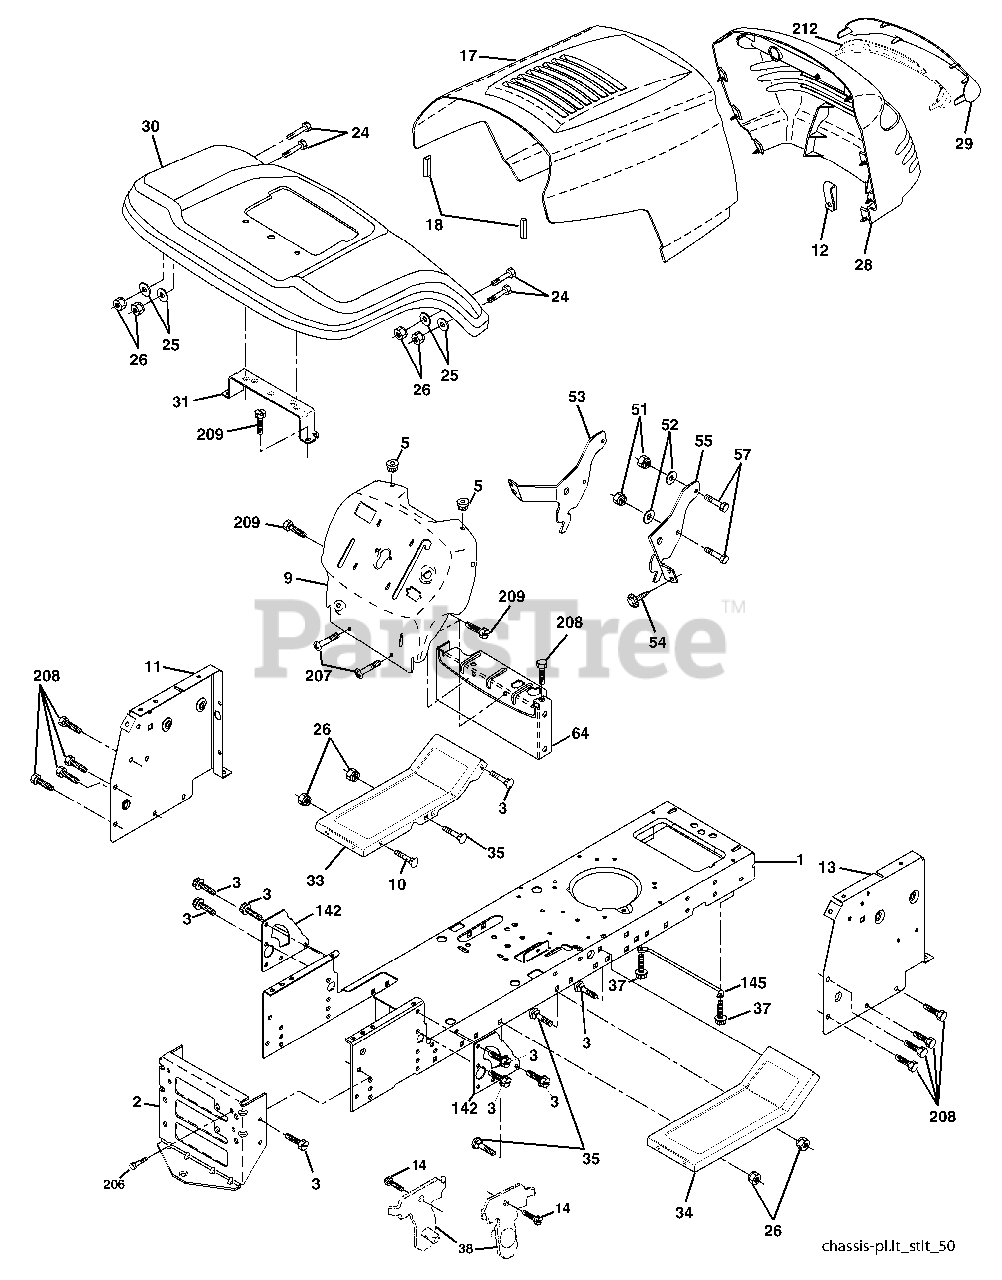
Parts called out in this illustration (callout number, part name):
1	Chassis
2	Drawbar
3	Screw 3/8-16 x.75
5	Bumper Hood/Dash
10	Bolt Carriage 3/8-16 x 1
11	Panel Dash Lh
12	Clip Tinnerman
13	Panel Dash Rh
14	Screw Thdrol 3/8-16 x 1-1/4
17	Hood LT/PL
18	Bumper Hood
24	Bolt Fin Hex 3/8-16 x 1 Gr 5
25	Washer 13/32 x 13/16 x 12 Ga
26	Nut Lock Hex W/Ins 3/8-16 Unc
28	Grille LT/PL
29	Lens LT/PL
30	Fender Footrest STLT Pnt
31	Bracket Support Fender
33	Footrest Pnt Lh
34	Footrest Pnt Rh
35	Bolt Rdhd Sht Sqnk 3/8-16 x 3/4
37	Screw Thdrol 6/16-18 x 1/2 TYT
38	Bracket Asm. Pivot Mower Rear
51	Nut Lock Hex W/Ins 1/4-20
52	Washer 9/32 x 7/8 x 16 Ga.
53	Bracjet Grukke Lh
54	Screw Hex Wshd 8-18 x 7/8
55	Bracket Grille Rh
57	Bolt Hex 1/4-20 x 3/4
64	Dash Lower STLT
142	Plate Reinforcement STLT
145	Rod Pivot Chassis/Hood
206	Bolt Shoulder 5/16-18
207	Screw Thdrol 5/16-18 x 1/2
208	Screw Thdrol 3/8-16 x 1/2
209	Screw Hex Wsh Thdr. 3/8-16 x 3/4
212	Insert Lens Reflect P/L LT
